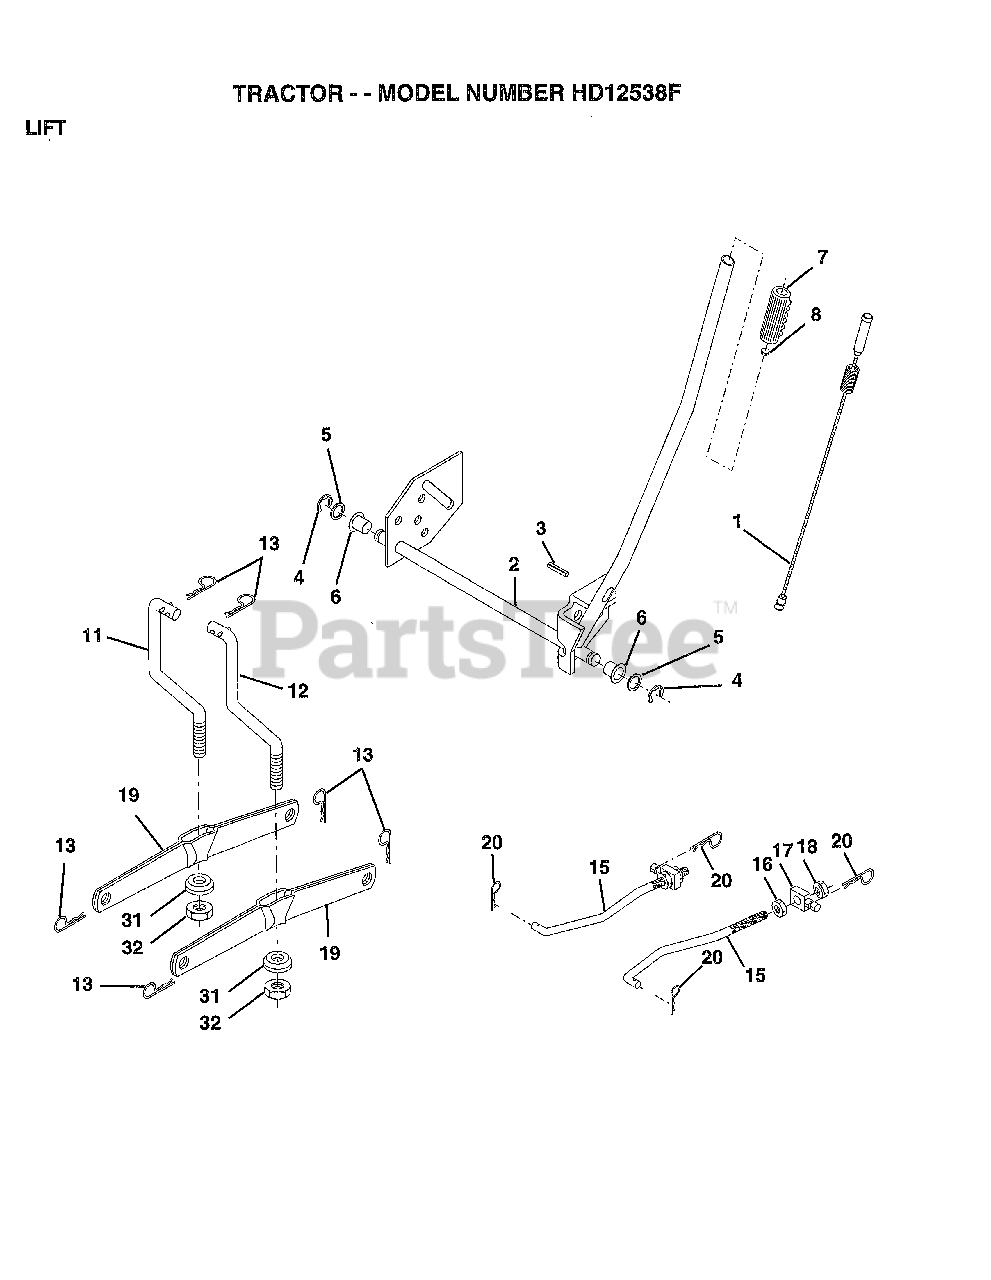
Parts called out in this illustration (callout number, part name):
1	WIRE ASM W.SPRING
2	"SHAFT ASM LIFT,RH"
3	PIN-GROOVE LT
5	WASHER
6	NYLON BEARING
7	GRIP
15	LINK.FRONT
16	NUT
17	TRUNION
18	NUT.LK.W/WSH.1/2.
19	ARM SUSP REAR
20	RETAINER SPRING
31	BEARING PVT LH
32	NUT.CROWNLOCK.3/8
